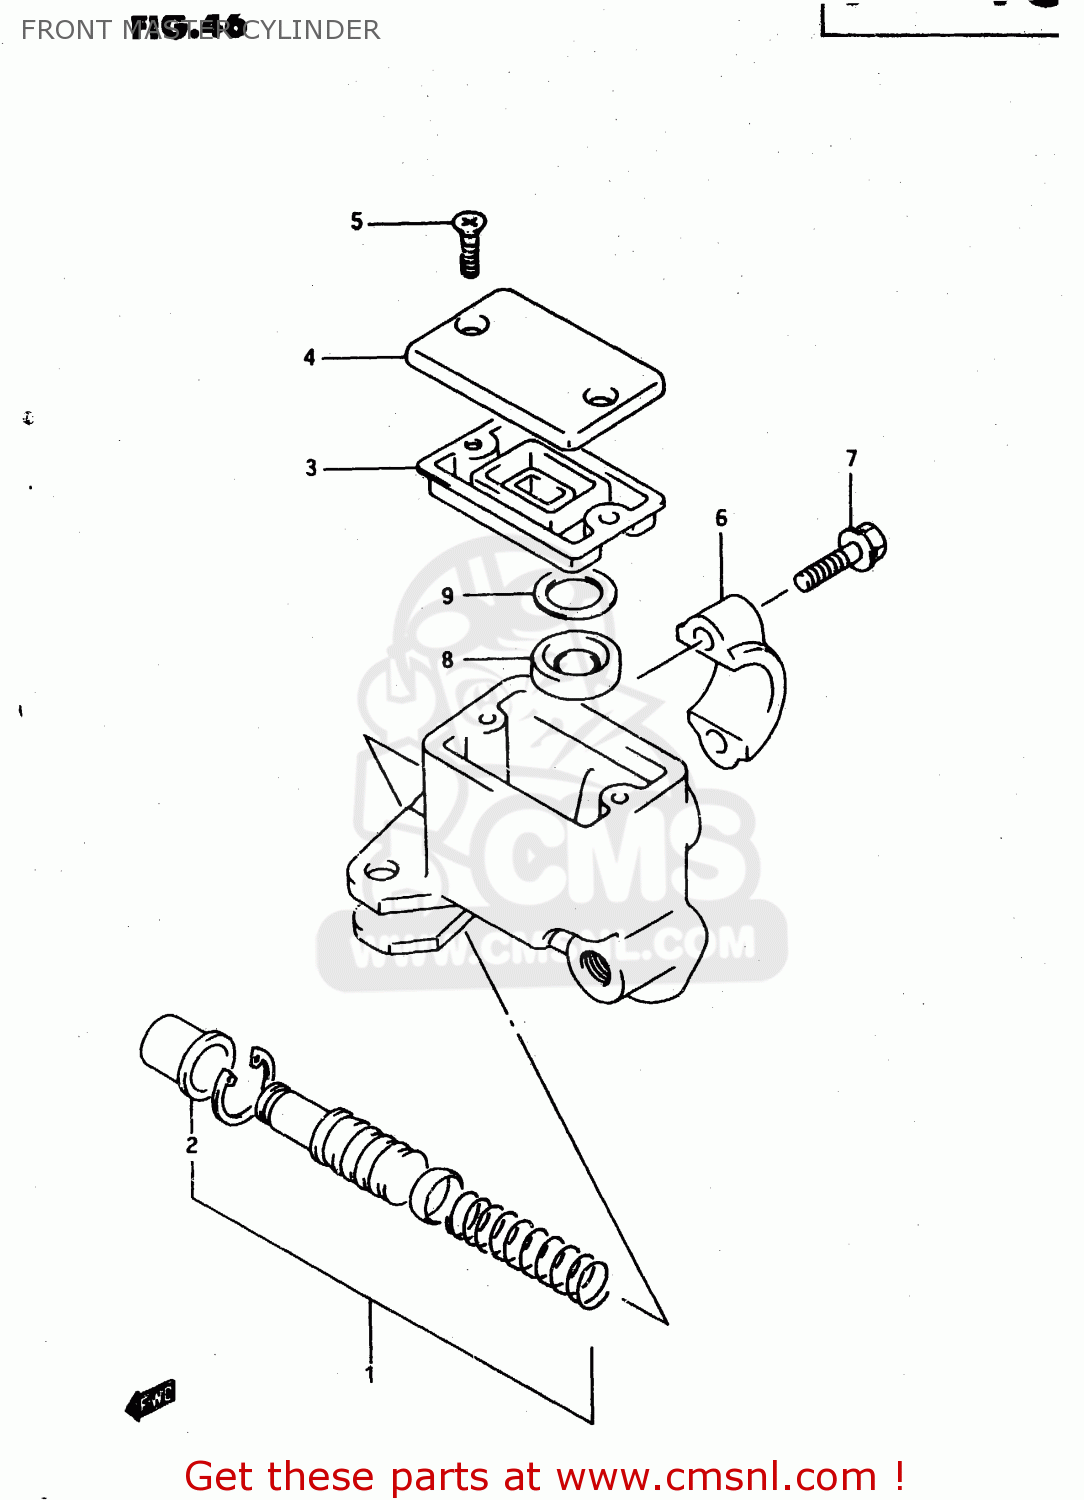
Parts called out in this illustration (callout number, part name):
1	PISTON & CUP SET
2	BOOT
3	DIAPHRAGM
4	CAP
5	SCREW
6	HOLDER
7	BOLT(6X25)
8	SEPERATOR
9	PLATE
